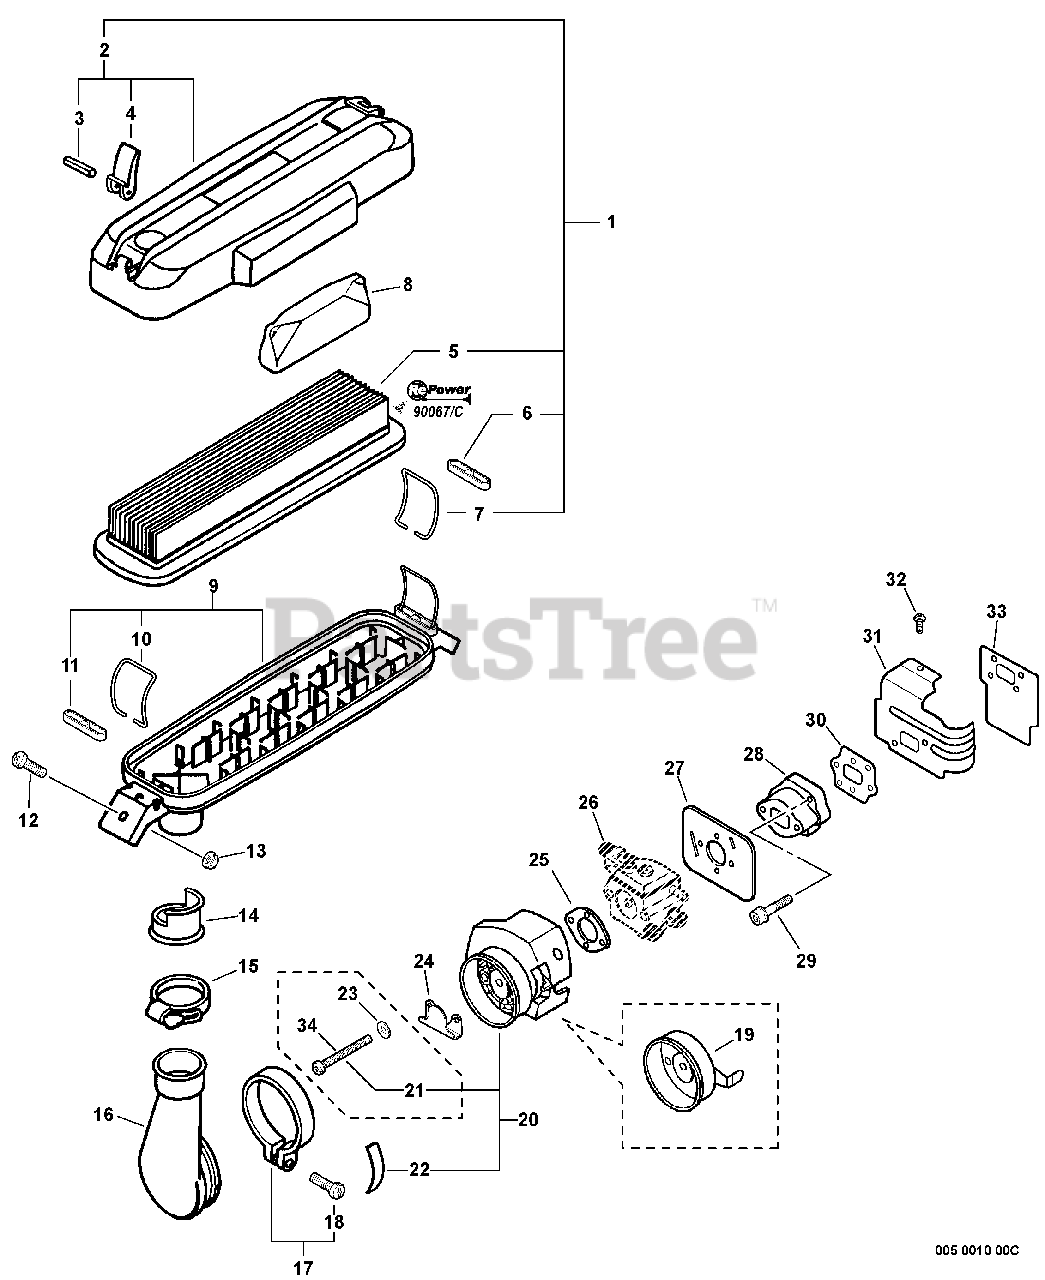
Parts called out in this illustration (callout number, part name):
1	AIR FILTER KIT
2	COVER ASSY, AIR FILTER
3	PIN, SPRING 3×25
5	FILTER, AIR
8	SILENCER
9	CASE ASSY, AIR FILTER
12	SCREW 5×14
13	NUT, FLANGE M5
14	COLLAR 27
16	ADAPTOR, INTAKE
17	CLAMP KIT
18	SCREW 5×25
20	BRACKET KIT, AIR FILTER
21	SCREW 5×57
22	LABEL, CHOKE
23	WASHER 6.5×13×1
24	PLATE, PREVENT
25	GASKET, INTAKE
26	CARBURETOR
27	GASKET, INTAKE
28	INSULATOR, INTAKE
29	BOLT 5×25
30	GASKET, INTAKE
31	COVER, CYLINDER
32	SCREW 5×10
33	HEAT SHIELD, INTAKE
34	SCREW 5×50
35	TUNE-UP KIT
